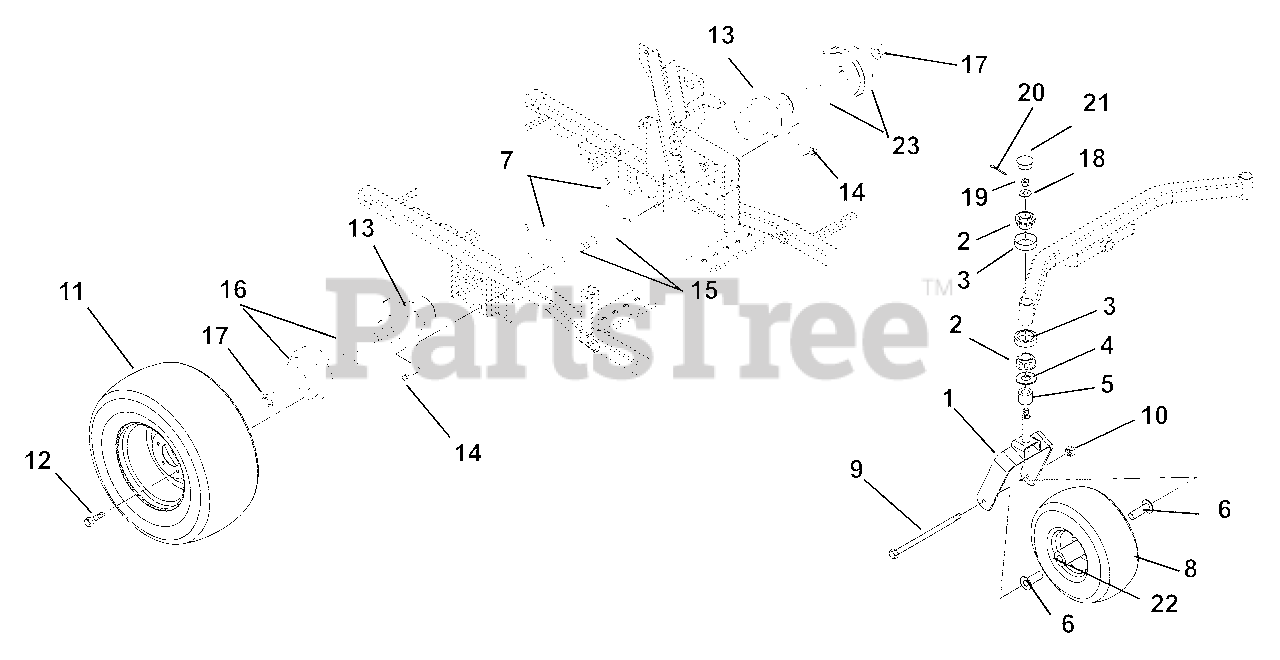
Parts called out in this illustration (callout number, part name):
1	Fork, Front
2	Bearing, Cone w/ Grease
3	Bearing, Cup 1.980 x .420
4	Bearing Seal 1.5 x 2 x .18
5	Spacer, PM, 1.03 I.D. x 1.5 O.D. x .375
6	Spacer, Wheel
7	Plate, Motor Support
8	Wheel/Tire Assembly
8	Tire, 15 x 6-6
9	Bolt, Hex .50-13 x 9.00 Grade 5
10	Nut, Locking Center .50-13
11	Tire/Wheel Assembly 24 x 12-12
11	Tire, Turfmaster 24 x 12-12
12	Bolt, Lug .50-20 x 1.38 Grade 8, 60 Degree
13	Hydraulic Wheel Motor
14	Nut, Locking Top Flange .50-13
15	Bolt, Wheel Motor .50-13 x 2.75
16	Brake, Right Hand Park
17	Nut , Lock Jam Patch
18	Washer, Flat Steel .755 x 1.375 x .062
19	Nut, Slotted .75-16
20	Pin, Cotter .16 x 1.00
21	Cap, Dust
22	Bearing, 25mm I.D. x 52mm OD x 15mm
23	Brake, Left Hand Park
